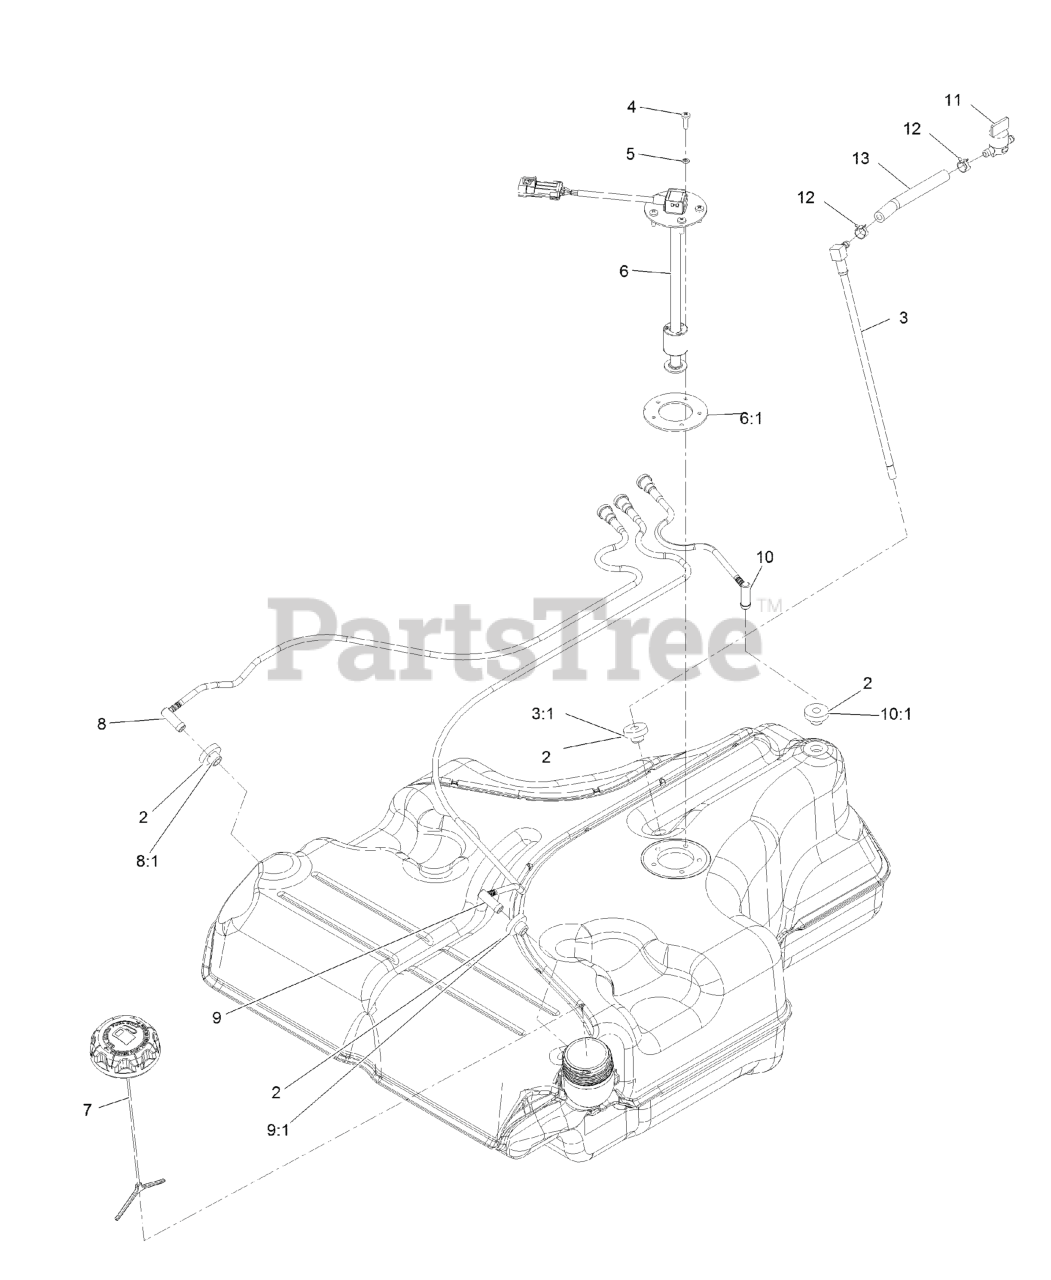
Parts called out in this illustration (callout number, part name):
2	BUSHING
3	FUEL LINE KIT (WITH GROMMET)
3:1	BUSHING
4	SCREW-PPH
5	WASHER-LOCK
6	FLOAT-SENDER, FUEL
6:1	Gasket-Sender
7	CAP-FUEL, RATCHETING
8	RH VENT LINE KIT (WITH GROMMET)
8:1	BUSHING
9	LH VENT LINE KIT (WITH GROMMET)
9:1	BUSHING
10	REAR VENT LINE KIT (WITH GROMMET)
10:1	BUSHING
11	VALVE-FUEL
12	CLAMP-HOSE
13	HOSE-FUEL
